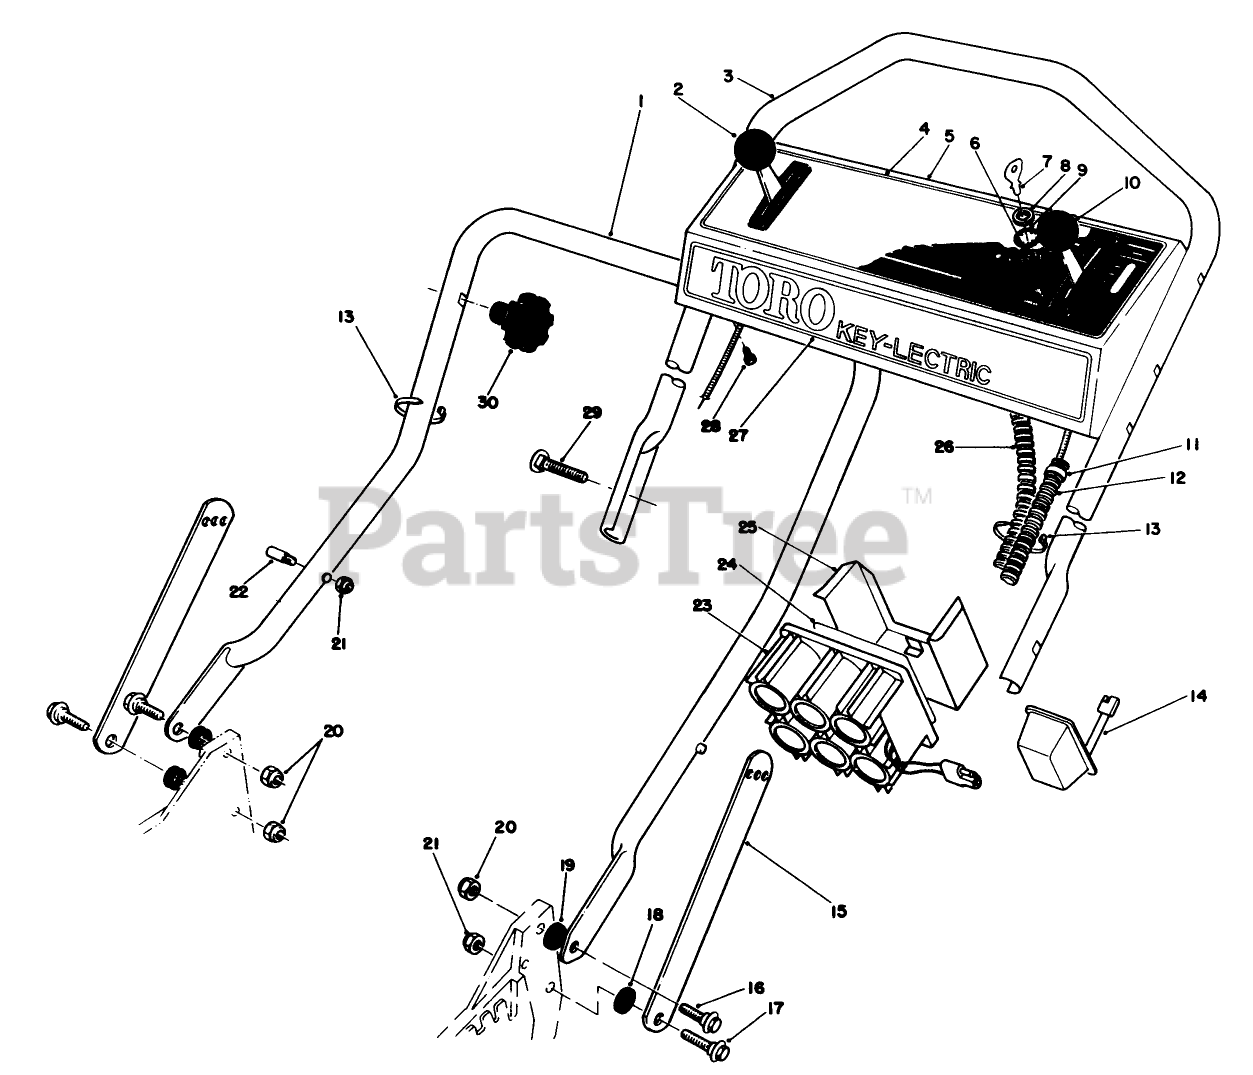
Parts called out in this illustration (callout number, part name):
2	GROUND SPEED CONTROL
6	STARTER SWITCH ASM
8	NUT-HH
9	WASHER-LOCK
10	SERVICE THROTTLE CONTRO
11	FITTING-RING
13	TIE-CABLE
16	SCREW-SHOULDER
17	SCREW-SHOULDER
18	SPACER
19	SPACER
20	NUT-LOCK, NI
21	NUT-LOCK, NI
22	HANDLE PIN
23	BATTERY ASSEMBLY,WET
26	WIRE HARNESS
28	SCREW-HWHTF
